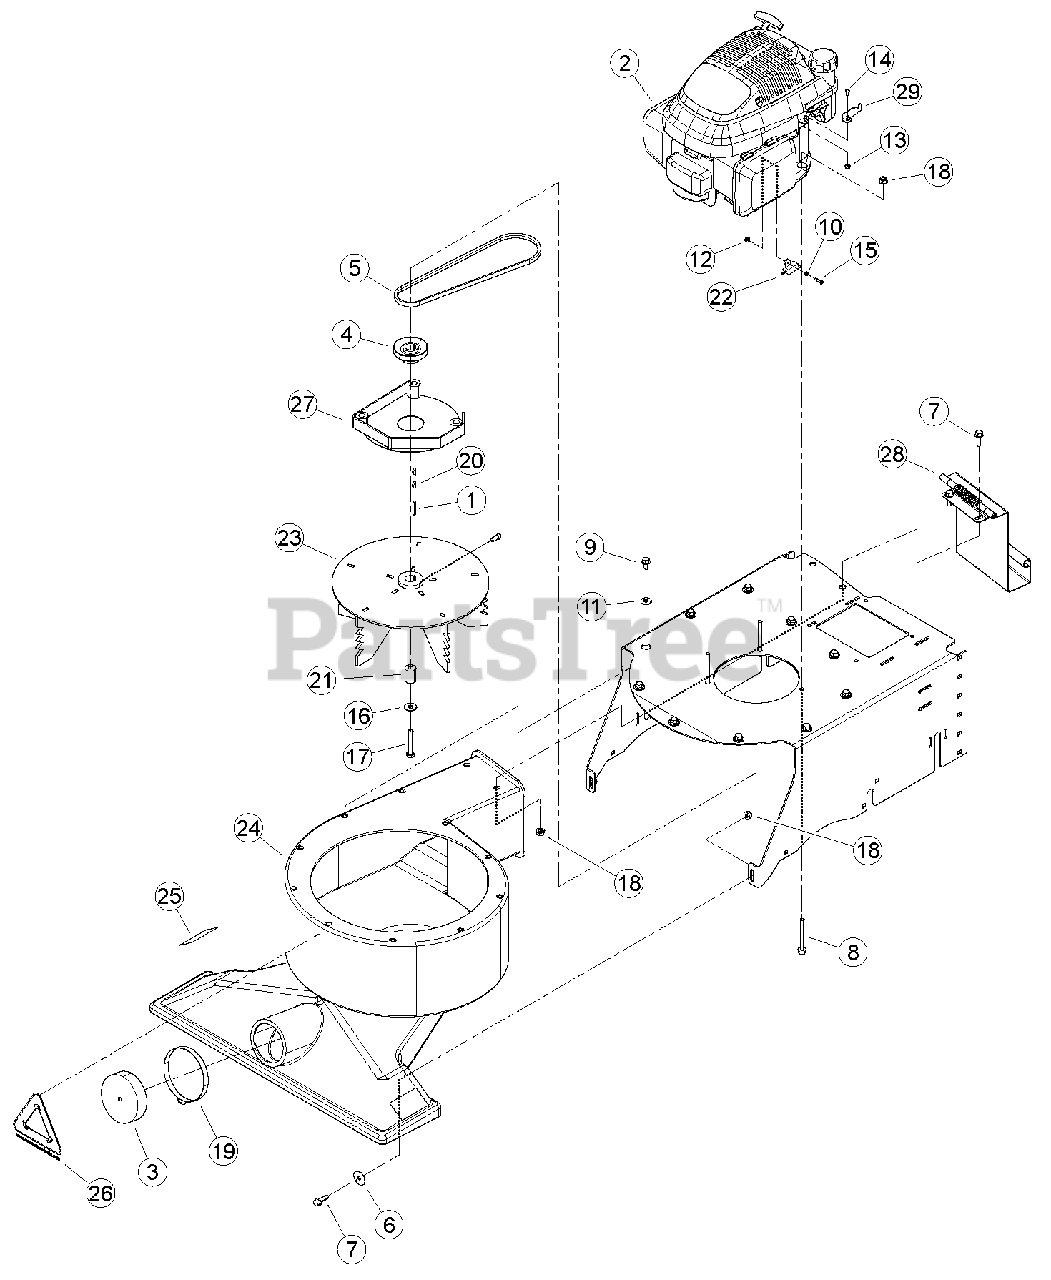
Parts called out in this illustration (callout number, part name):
1	KEY, 3/16 SQ X 1-1/4" PLAIN
2	ENGINE, 190CC B+S INTEK/IC VERTICAL (WV190S ONLY) (FOR SERVICE SEE ENGINE OWNER'S MANUAL OR NEAREST BRIGGS & STRATTON INDUSTRIAL ENGINE DEALER)
3	CAP, ROUND VINYL
4	PULLEY, 2.85 O.D. X 7/8" BORE
5	BELT, SP BEARVAC
6	WASHER, 5/16" FENDER ZP
7	BOLT, 5/16 X 1 FLANGE NC
8	BOLT, 5/16 X 2-3/4 FLANGE NC (WV190S ONLY)
9	BOLT, 5/16 X 5/8 FLANGE NC
10	WASHER, #8 SAE (WV160S ONLY)
11	WASHER, 5/16 FLAT
12	NUT, 8-32 NYLOCK (WV160S ONLY)
13	NUT, 10/24 NYLOCK TYPE NM ZP (WV160S ONLY)
14	SCREW, MCH 10-24 X 1/2" PAN HD PH ZP (WV160S ONLY)
15	SCREW, MCH 8-32 X 3/4 PHP RDHD (WV160S ONLY)
16	WASHER, 3/8 GR8 USS ZP
17	BOLT, 3/8 X 2-1/4" NF GR8 ZP HHCS
18	NUT, 5/16-18 NYLOCK-FLANGE
19	CLAMP, 4" HOSE
20	KEY, 3/16 X 5/32" / 4MM WOODRUFF JUMP
21	SPACER, .88 X 1.25
22	SWITCH, HONDA ENGINE KILL (WV160S ONLY)
23	WELDMENT, BEARVAC ROTOR
24	ASSEMBLY, FAN INTAKE HOUSING W/ DECALS (INCLUDES ITEMS 25 & 26)
25	DECAL, DANGER
26	LOGO, COLLECT IT (WHITE)
27	WELDMENT, BEARVAC ENGINE SUPPORT
28	ASSEMBLY, EXHAUST DOOR
29	PLATE, HONDA BRAKE HOLDER (WV160S ONLY)
